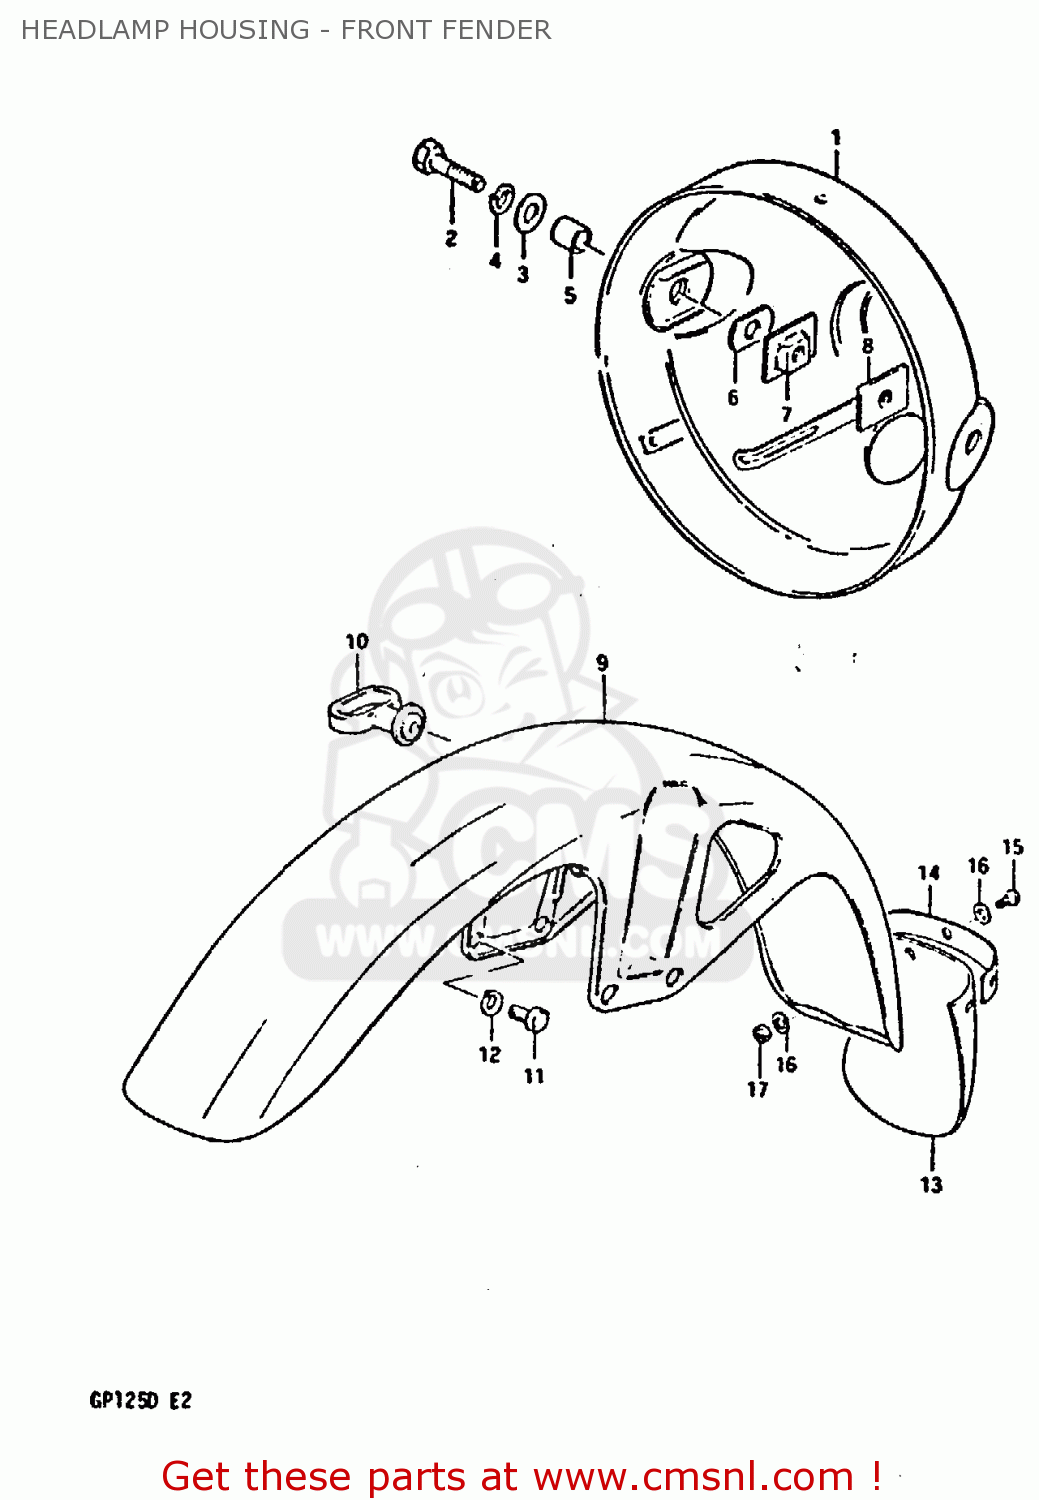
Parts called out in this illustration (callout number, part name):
1	HOUSING,HEADLAMP
2	BOLT
3	WASHER
4	LOCK WASHER
5	SPACER (8.8X12X7)
6	CUSHION
7	PLATE,HEADLAMP HOUSING
8	PLATE,HEADLAMP HOUSING
9	FENDER,FRONT
10	GUIDE,CABLE
11	BOLT
12	LOCK WASHER
13	FLAP,MUD
14	PLATE,MUDFLAP
15	SCREW 4X10
16	WASHER
17	NUT 4MM
